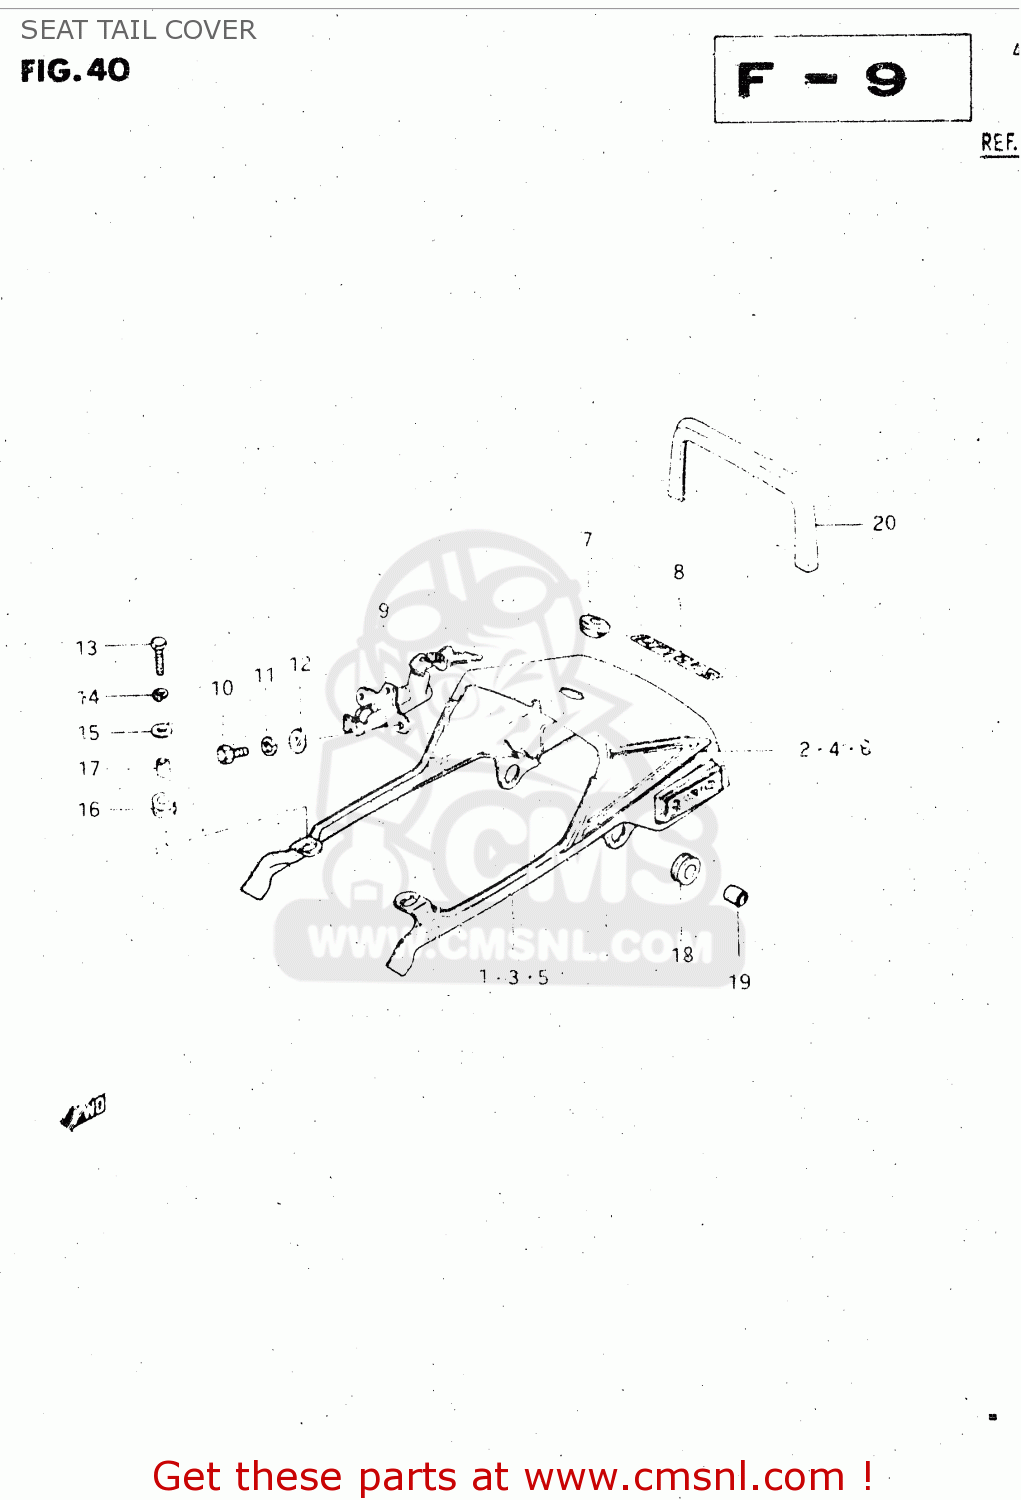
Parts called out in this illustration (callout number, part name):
1	COVER, SEAT TAIL (BLACK)
2	TAPE SET
3	COVER, SEAT TAIL (RED)
4	TAPE SET
5	COVER, SEAT TAIL (BLUE)
6	TAPE SET
7	GROMMET,SEAT LOCK HOLE
8	EMBLEM,SEAT TAIL COVER
9	LOCK SET,SEAT
10	BOLT
11	LOCK WASHER
12	WASHER
13	BOLT
14	LOCK WASHER
15	WASHER(6,5X22X1.6)
16	CUSHION
17	SPACER(6.5X10.5X12)
18	CUSHION
19	SPACER
20	GROMMET
